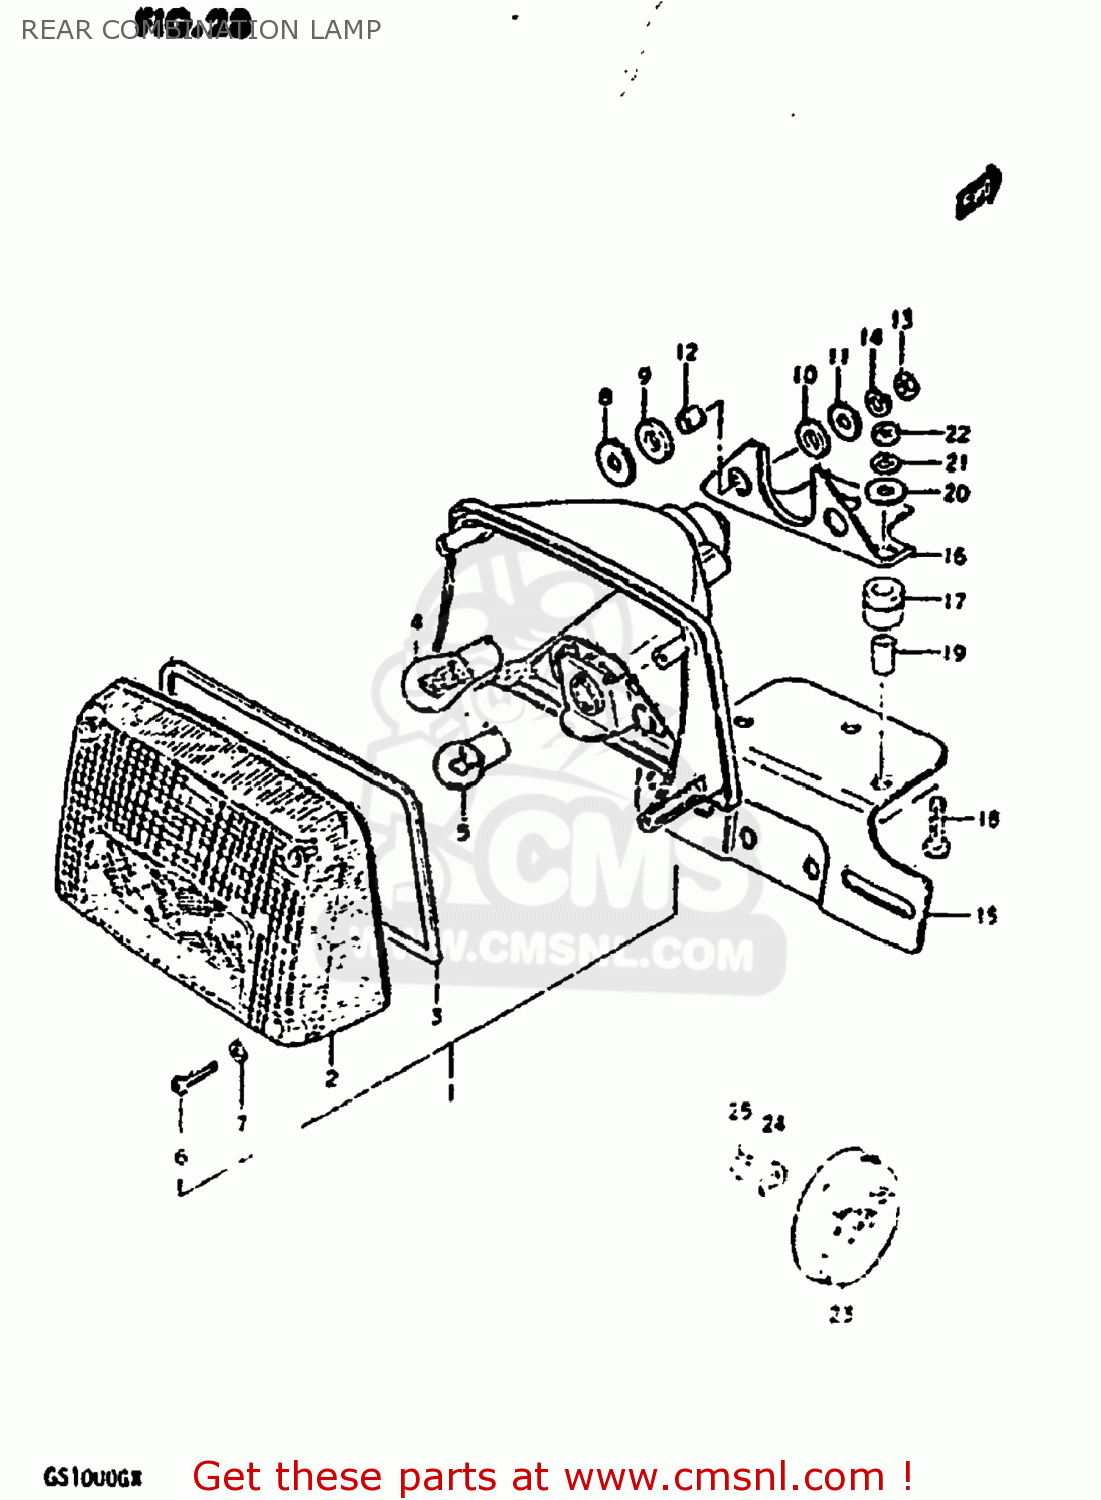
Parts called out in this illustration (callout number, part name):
1	LAMP ASSEMBLY,REAR COMBINATION
2	LENS
3	GASKET (NAS)
4	BULB(12V23W)
5	BULB
6	BOLT
7	GASKET (NAS)
8	WASHER
9	CUSHION
10	CUSHION
11	WASHER(6,5X22X1.6)
12	SPACER(6.1X9X7.5)
13	NUT
14	LOCK WASHER
15	PLATE,REAR LICENSE
16	BRACKET,LICENSE PLATE
17	CUSHION, BRACKET
18	BOLT
19	SPACER (6.4X9X15.5)
20	WASHER
21	LOCK WASHER
22	NUT
23	REFLEX REFLECTOR,RR
24	WASHER
25	NUT
